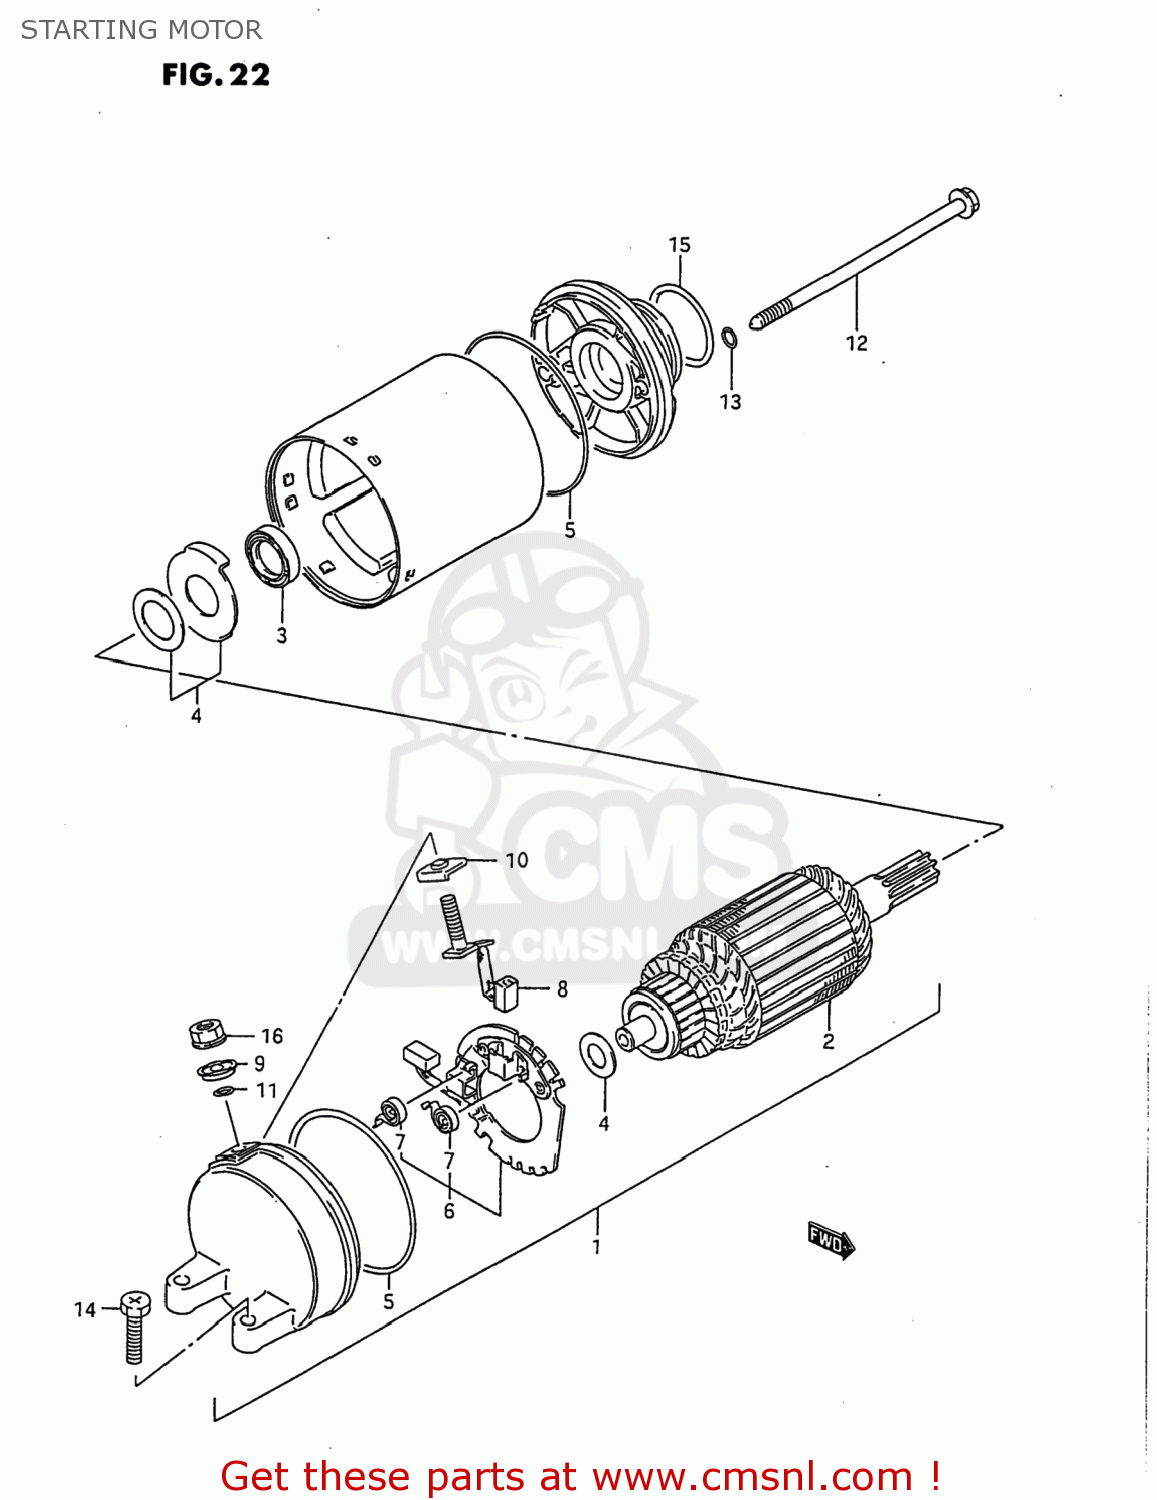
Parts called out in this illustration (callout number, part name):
1	MOTOR ASSEMBLY,STARTING
2	ARMATURE
3	SEAL,OIL
4	SHIM SET,STARTING MOTOR
5	O RING
6	HOLDER,BRUSH
7	SPRING
8	BRUSH SUB ASSY,STARTING MOTOR
9	BUSHING
10	BUSH,B
11	O RING
12	BOLT
13	O RING
14	SCREW (6X25)
15	O RING(D:3,ID:24.5)
16	NUT
